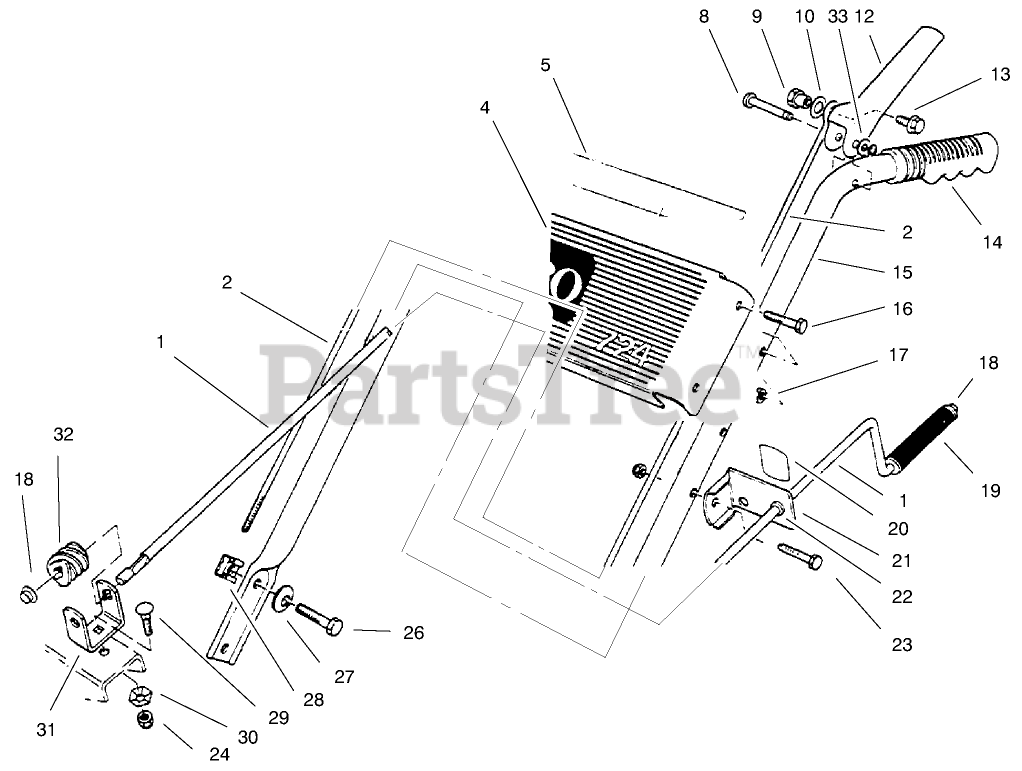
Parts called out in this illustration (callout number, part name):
1	ROD-CONTROL, CHUTE
2	LINK-UPPER
4	Panel-Escutcheon Ref.
5	DECAL-ESCUTHEON BACK
8	PIN-LEVER, CONTROL
9	POST-MOUNTING, LINKAGE
10	WASHER-FLAT
12	HANDLE-CONTROL
13	SCREW-HHF
14	GRIP-HANDLE
15	HANDLE-LEFT
16	SCREW-HH
17	NUT-LOCK, NI
18	RETAINER-PUSH ON
19	GRIP-CONTROL, CHUTE
20	DECAL-CHUTE DIRECTION
21	Bracket-Chute Control (Incl. Ref.# 20 & 22)
22	Bushing
23	SCREW-HH
24	NUT-LOCK, NI
26	SCREW-HH
27	WASHER-BELLEVILLE
29	SCREW-CARR
30	WASHER-LOCK
31	BRACKET-WORM
32	GEAR-WORM, CHUTE
33	RING-CLIP
